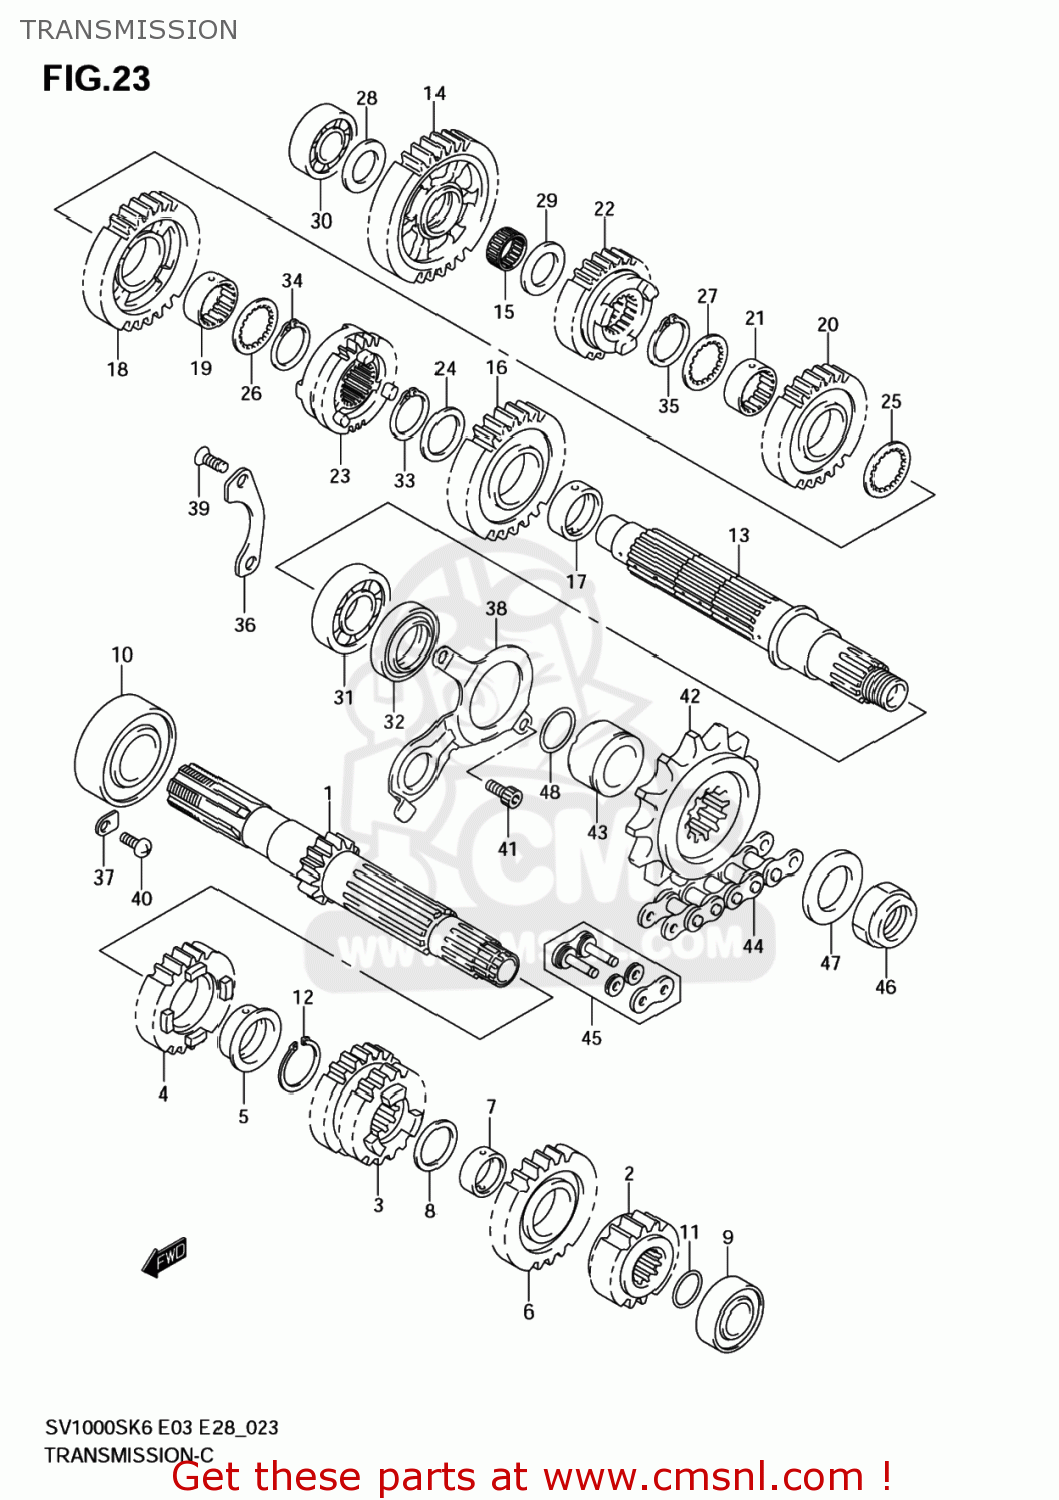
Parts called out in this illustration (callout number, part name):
1	SHAFT,COUNTER(NT:12)
2	GEAR,2ND DRIVE(NT:15)
3	GEAR,3RD & 4TH DRIVE(NT:18/22)
4	GEAR,5TH DRIVE(NT:23)
5	BUSH,5TH DRIVE GEAR
6	GEAR,6TH DRIVE(NT:24)
7	BUSH,6TH DRIVE GEAR
8	SHIM(22X30X1)
9	BEARING(20X47X14)
10	BEARING(25X62X17)
11	O RING(D:1.9,ID:16.6)
12	CIRCLIP
13	SHAFT,DRIVE
14	GEAR,1ST DRIVEN(NT:32)
15	BEARING(22X26X11)
16	GEAR,2ND DRIVEN(NT:29)
17	BUSH,2ND DRIVEN GEAR
18	GEAR,3RD DRIVEN(NT:27)
19	BUSH,3RD DRIVEN GEAR
20	GEAR,4TH DRIVEN(NT:27)
21	BUSH,3RD DRIVEN GEAR
22	GEAR,5TH DRIVEN(NT:25)
23	GEAR,6TH DRIVEN(NT:24)
24	WASHER(27X36X1)
25	WASHER,LOCK
26	WASHER,3RD & 4TH DRIVEN
27	WASHER,3RD & 4TH DRIVEN
28	SHIM(20X34X1)
29	SHIM(22X34X1)
30	BEARING(20X52X15)
31	BEARING(28X68X20)
32	SEAL,OIL(38X52X8)
33	CIRCLIP
34	CIRCLIP
35	CIRCLIP
36	RETAINER,DRIVE SHAFT BEARING
37	RETAINER
38	RETAINER,DRIVE SHAFT OIL SEAL
39	SCREW(6X12)
40	SCREW
41	BOLT
42	SPROCKET,ENGINE(NT:17)
43	SPACER,ENGINE SPROCKET
44	CHAIN,DRIVE
45	JOINT SET,CHAIN
46	NUT
47	SHIM(25X40X1.5)
48	O RING(D:2.4,ID:23.7)
